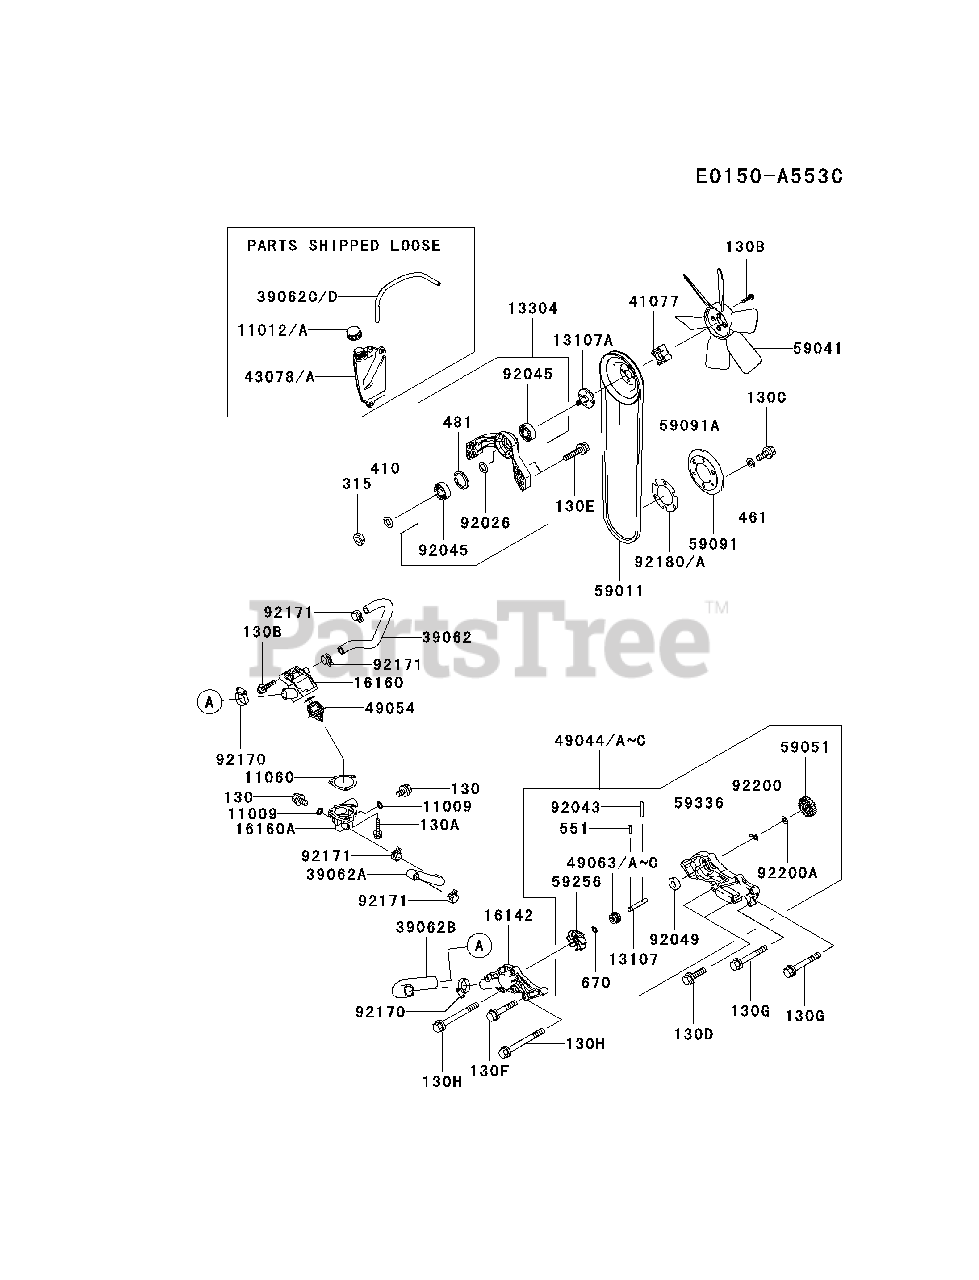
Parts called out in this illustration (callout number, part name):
130	BOLT-FLANGED
130A	BOLT-FLANGED
130B	BOLT-FLANGED
130C	BOLT-FLANGED
130D	BOLT-FLANGED
130E	BOLT-FLANGED
130F	BOLT-FLANGED
130G	BOLT-FLANGED
130H	BOLT-FLANGED
315	NUT-HEX-FINE
410	W-PLAIN-S
461	WASHER-SPRING
481	CIRCLIP
551	PIN-DOWEL
670	O RING
92180	SHIM,T=0.6
92180A	SHIM,T=1.2
92200A	WASHER,10.2X19X0.8
